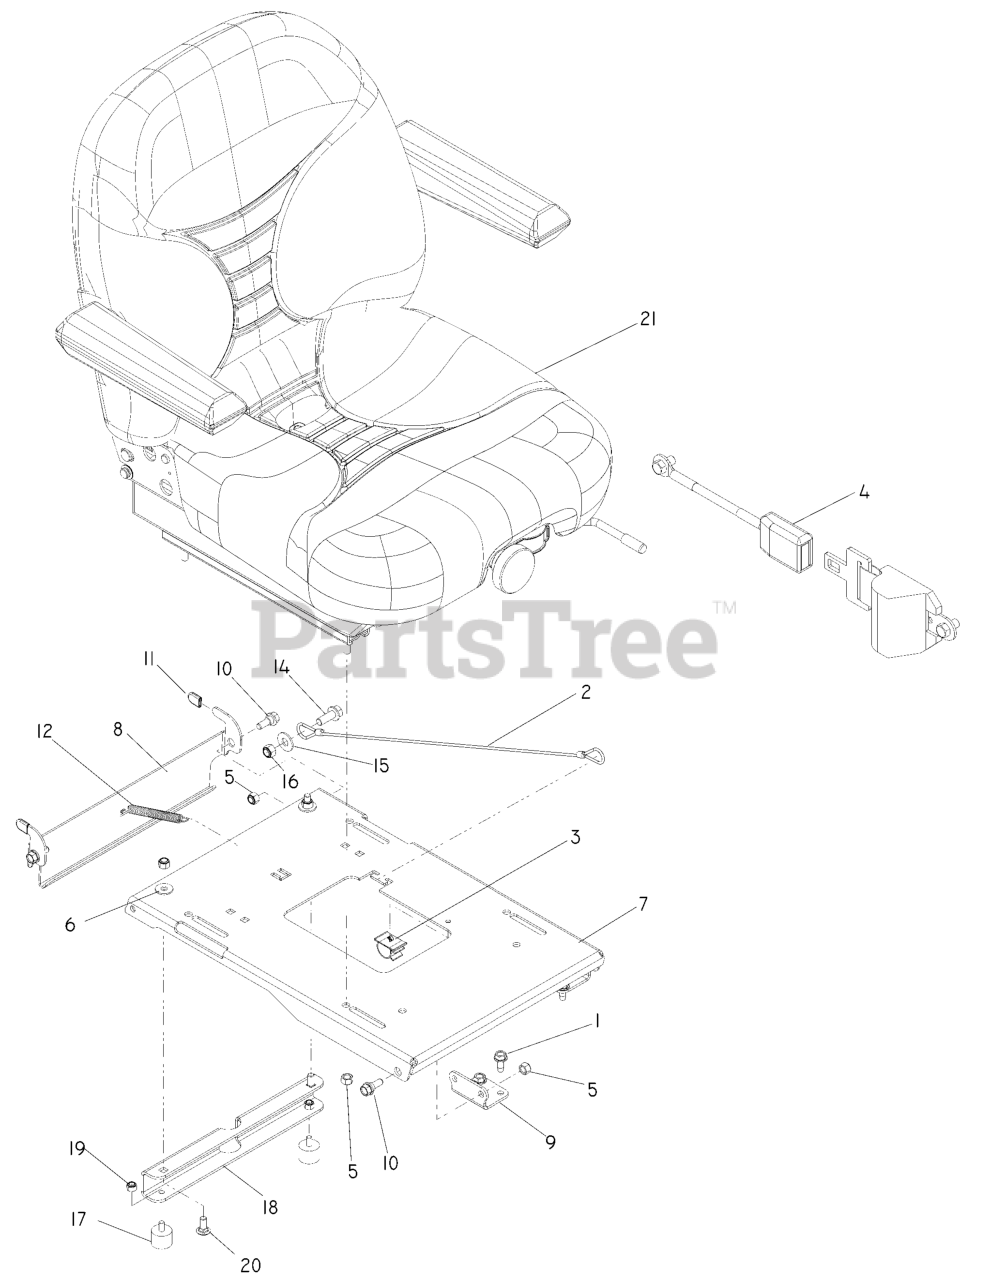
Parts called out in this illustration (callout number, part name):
1	BOLT 5/16-18 X 3/4
2	SEAT LANYARD
3	PUSH-MOUNT WIRE CLIP
4	SEAT BELT, RETRACTABLE
5	NUT 5/16 NYLOC
6	WASHER 5/16 FLAT
7	PAN, SEAT - BLACK
8	LATCH, SEAT - BLACK
9	PIVOT, SEAT PAN
10	SB 5/16-18 HEX HD GD5, BLK ZN
11	GRIP, VINYL, .09 X .495 X.75
13	HCS 5/16C X 1
14	4CS 3/8C X 1 SERRATED HEAD
15	WASHER 3/8 FLAT
16	NUT 3/8-16 NYLOC
17	STUD/PLATE MOUNT
18	STANDOFF, SEAT PAN
19	NUT.1/4-20.HEX.NYLOC.ZD
20	BOLT 5/16C X 3/4" CARRIAGE
21	SEAT - SUSP, NC SWITCH
